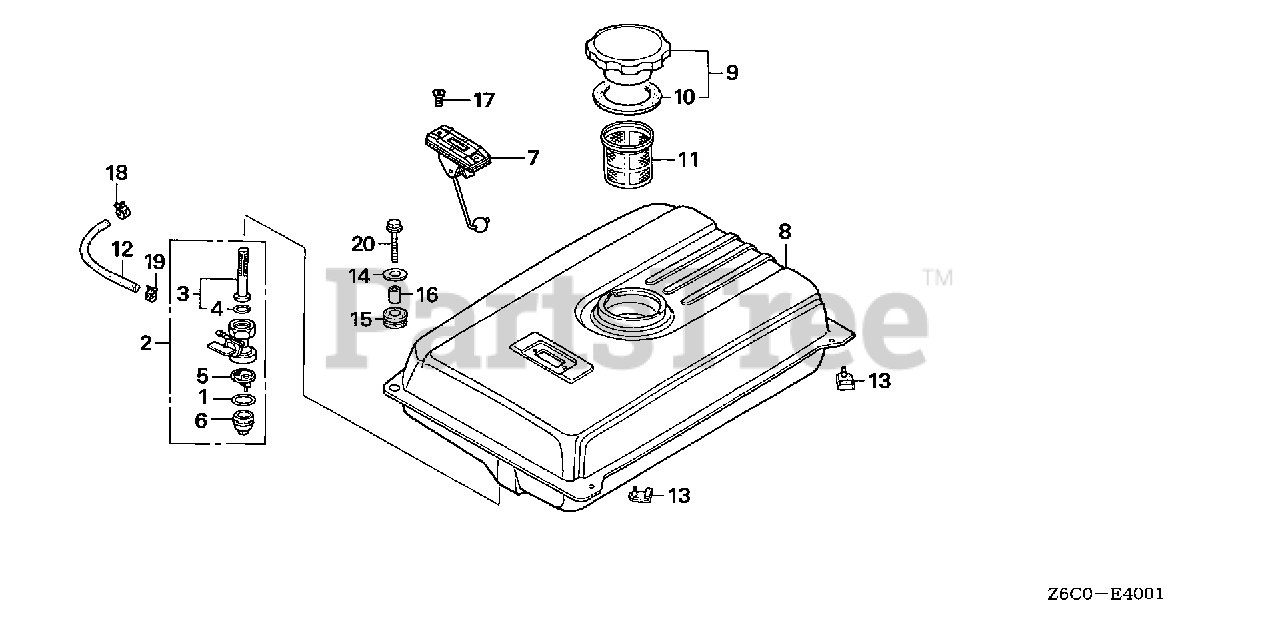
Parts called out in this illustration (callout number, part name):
1	GASKET, FUEL STRAINER CUP
2	PETCOCK ASSY.
3	SCREEN SET, FUEL STRAINER
4	O-RING (9.0X1.3)
5	FILTER, CUP
6	CUP, FUEL STRAINER
7	METER ASSY., FUEL
8	TANK, FUEL *T73* (EXEN GRAY)
9	CAP, FUEL FILLER
10	GASKET, FUEL FILLER CAP
11	FILTER, FUEL
12	TUBE, FUEL (EXEN)
12	HOSE, FUEL (FKM)(EXEN)
13	RUBBER, TANK MOUNTING
14	WASHER, TANK CUSHION
15	CUSHION, TANK RUBBER
16	COLLAR, TANK CUSHION
17	SCREW, FLAT (5X10)
18	CLIP, TUBE (D8.5)
19	CLIP, TUBE (10.5MM)
20	BOLT, FLANGE (6X35)
